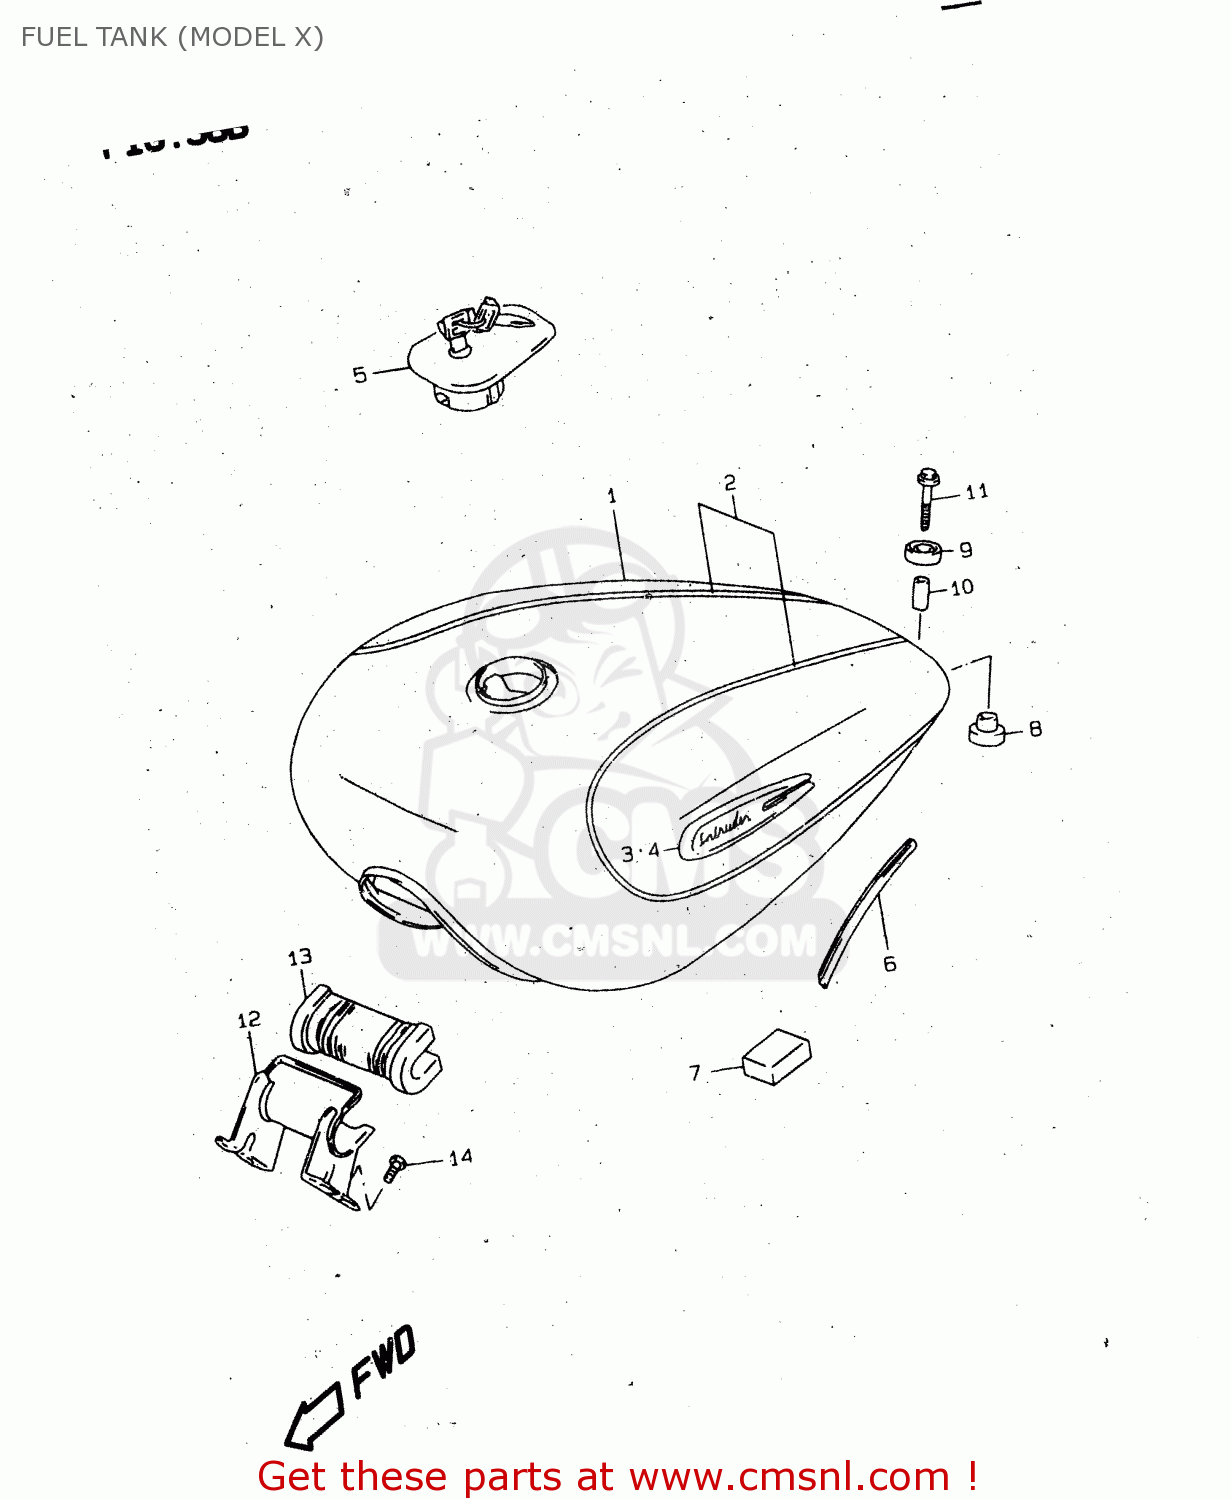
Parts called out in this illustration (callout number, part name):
1	TANK ASSY,FUEL
2	TAPE SET,FUEL TANK STRIPE
3	EMBLEM,FUEL TANK,R
4	EMBLEM,FUEL TANK,L
5	CAP SET,FUEL TANK
6	MOLDING
7	CUSHION
8	CUSHION
9	CUSHION
10	SPACER(6.5X9X22.5)
11	BOLT
12	BRACKET,TANK
13	CUSHION,FUEL TANK FR
14	SCREW
